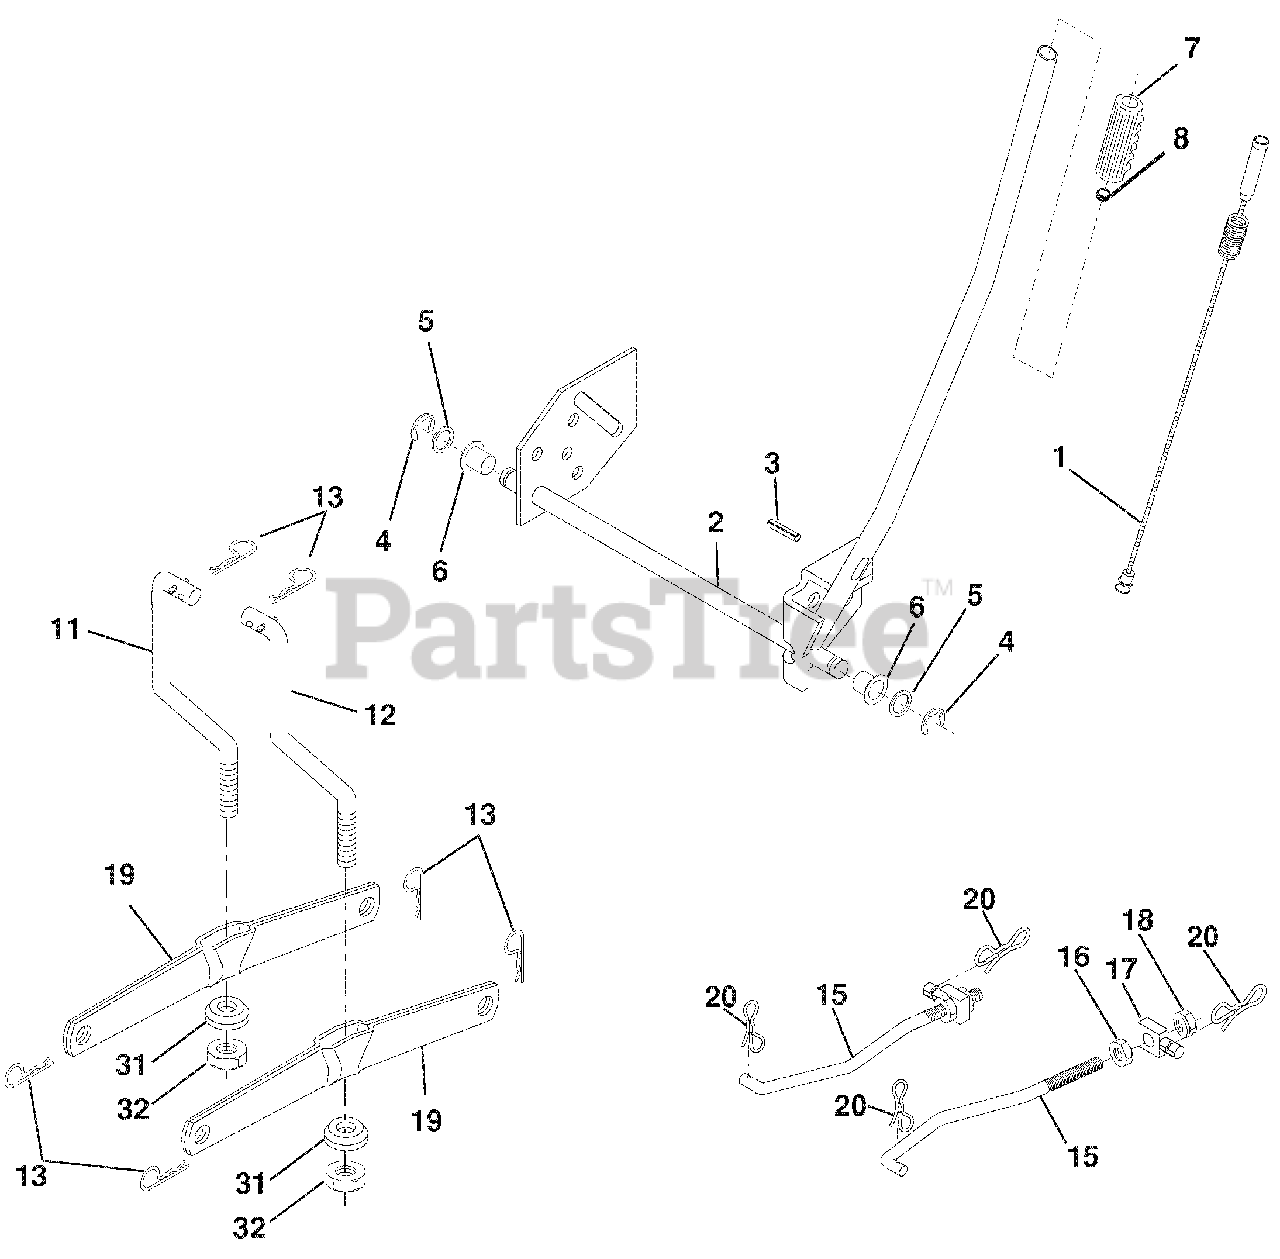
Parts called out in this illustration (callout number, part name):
1	PLUNGER ASM LIFT LEVER
2	SHAFT ASM LIFT RH
3	PIN GROOVE 1 500 ZINC
4	E RING #5133-62
5	WASHER 21/32 X 1 X 21 GA.
6	BEARING.NYLON.BLK..629 ID.
7	GRIP HANDLE
8	BUTTON PLUNGER BLACK
11	LINK LIFT LH FIXED LENGTH
12	LINK LIFT RH FIXED LENGTH
13	RETAINER.SPRING
15	LINK FRONT
16	NUT JAM HEX 1/2-13 UNC
17	TRUNNION
18	NUT LOCK W/WSH 1/2-13 UNC
19	ARM SUSPENSION REAR
20	PIN.COTTER.7/16.BOW TIE LOCK
31	BEARING PVT LIFT
32	NUT.CROWNLOCK.3/8-24
